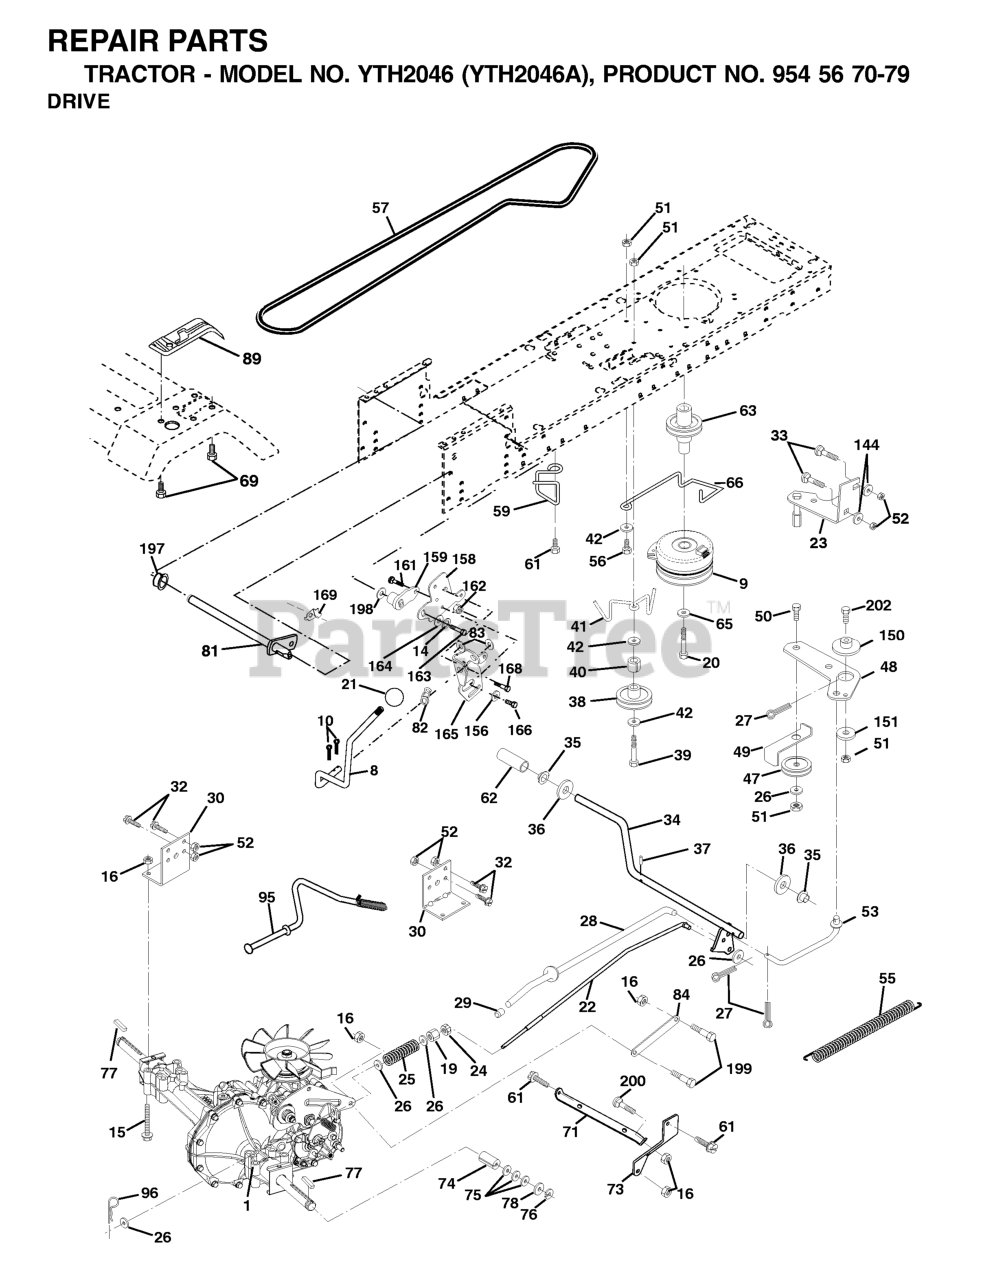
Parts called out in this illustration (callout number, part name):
8	ROD SHIFT FENDER
9	ELECTRIC CLUTCH
10	PIN COTTER
14	LOCKWASHER
15	BOLT HEX 5/16-18 GR 5
16	NUT.71038.31-18.HEX.NYLOCK
19	NUT
20	BOLT HEX
21	KNOB.DELUXE.(PISTOL.GRIP).BLAC
22	ROD BRAKE HYDRO
24	NUT
25	SPRING ROD LT
26	WASHER
27	COTTER PIN
28	ROD BRAKE PARK LT
29	PLUNGER CAP
30	BRKT, TRNSXLE MNT 20"
32	BOLT
33	RP BOLT 5/16-18 X3/4 ZN/YEL GR
34	SHAFT, FOOT PEDAL
35	BEARING.NYLON
36	WASHER LT
37	DRIVE PIN
38	FLAT IDLER PULLEY
41	KEEPER.BELT.IDLER.FLAT
42	WASHER
47	IDLER PULLEY
48	BELLCRANK, CLUTCH
49	RETAIN BELT
50	BOLT
52	LOCKNUT
53	LINK, CLUTCH LT
55	SPRING, RETURN LT
57	DRIVE BELT, LTH & YTH TRACTORS
59	KEEPER, BELT CENTER
61	SCREW 3/8-16X3/4
62	PEDAL COVER T
63	PULLEY, CLUTCH ELECT EVX
65	LOCKWASHER
66	KEEPER BELT ENGINE
69	SCREW.HI-LO.CONSOLE
71	STRAP TORQUE LH HYDRO
73	STRAP TORQUE RH HYDRO
74	SPACER AXLE
77	SQUARE KEY
81	SHAFT ASM CROSS TAPERED
82	SPRING,TORSION
83	WASHER
84	LINK TRANSAXLE
95	CONTROL ASM. BYPASS HYDRO
96	RETAINER M
144	Washer 11/32 x 5/8 x 16 Ga SD
150	BUSHING.BELLCRANK.GRD.DR
151	WASHER 12/32X2X10GA
156	WASHER.SRRTD.5/16
158	BRACKET
159	HUB
161	BOLT
162	NUT.CROWNLOCK.1/4
163	BOLT
164	Washer 5/8 x .281 x 10 Ga.
165	RP BRACKET
168	BOLT.SHOULDER.5/16-18X
169	PLATE.FASTENING.CROSS.SHAFT
197	NYLINER SNAP 5/8" ID
198	WASHER.NYL.7/8IDX.105"HYD CR
199	BOLT SHOULDER 5/16-18 UNC
200	BOLT
201	SCREW
202	BOLT.3/8-16X1.50
